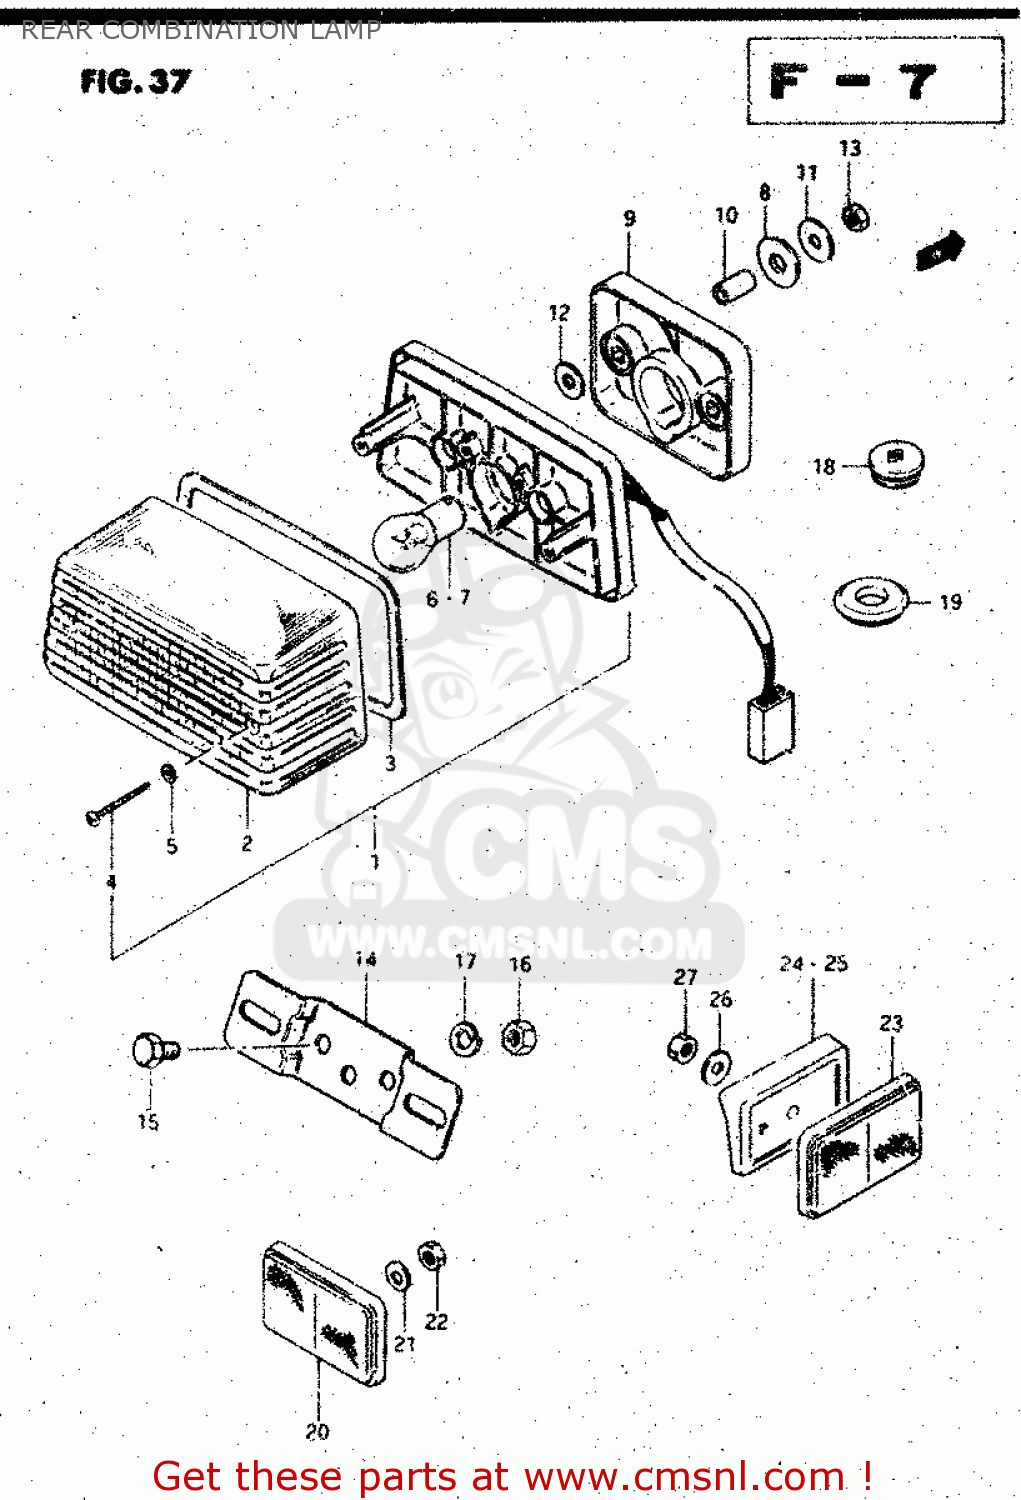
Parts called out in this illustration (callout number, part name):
1	LAMP ASSY, REAR COMBINATION
2	LENS
3	GASKET (NAS)
4	SCREW
5	GASKET (NAS)
6	BULB(12V21/5W)
7	BULB(12V23W)
8	CUSHION,RR COMBINATION LAMP
9	CUSHION,RR COMB LAMP NO.1
10	SPACER (6.1X8X12)
11	WASHER (5.5X20X1.2)
12	WASHER(5.5X16X1.2)
13	NUT
14	BRACKET,LICENSE PLATE
15	BOLT
16	NUT
17	WASHER,LOCK
18	CAP(OD:24)
19	GROMMET
20	REFLEX REFLECTOR,RR
21	WASHER
22	NUT
23	REFLECTOR,REFLEX
24	SPACER, RH
25	SPACER, LH
26	WASHER(5.2X16X1)
27	NUT
